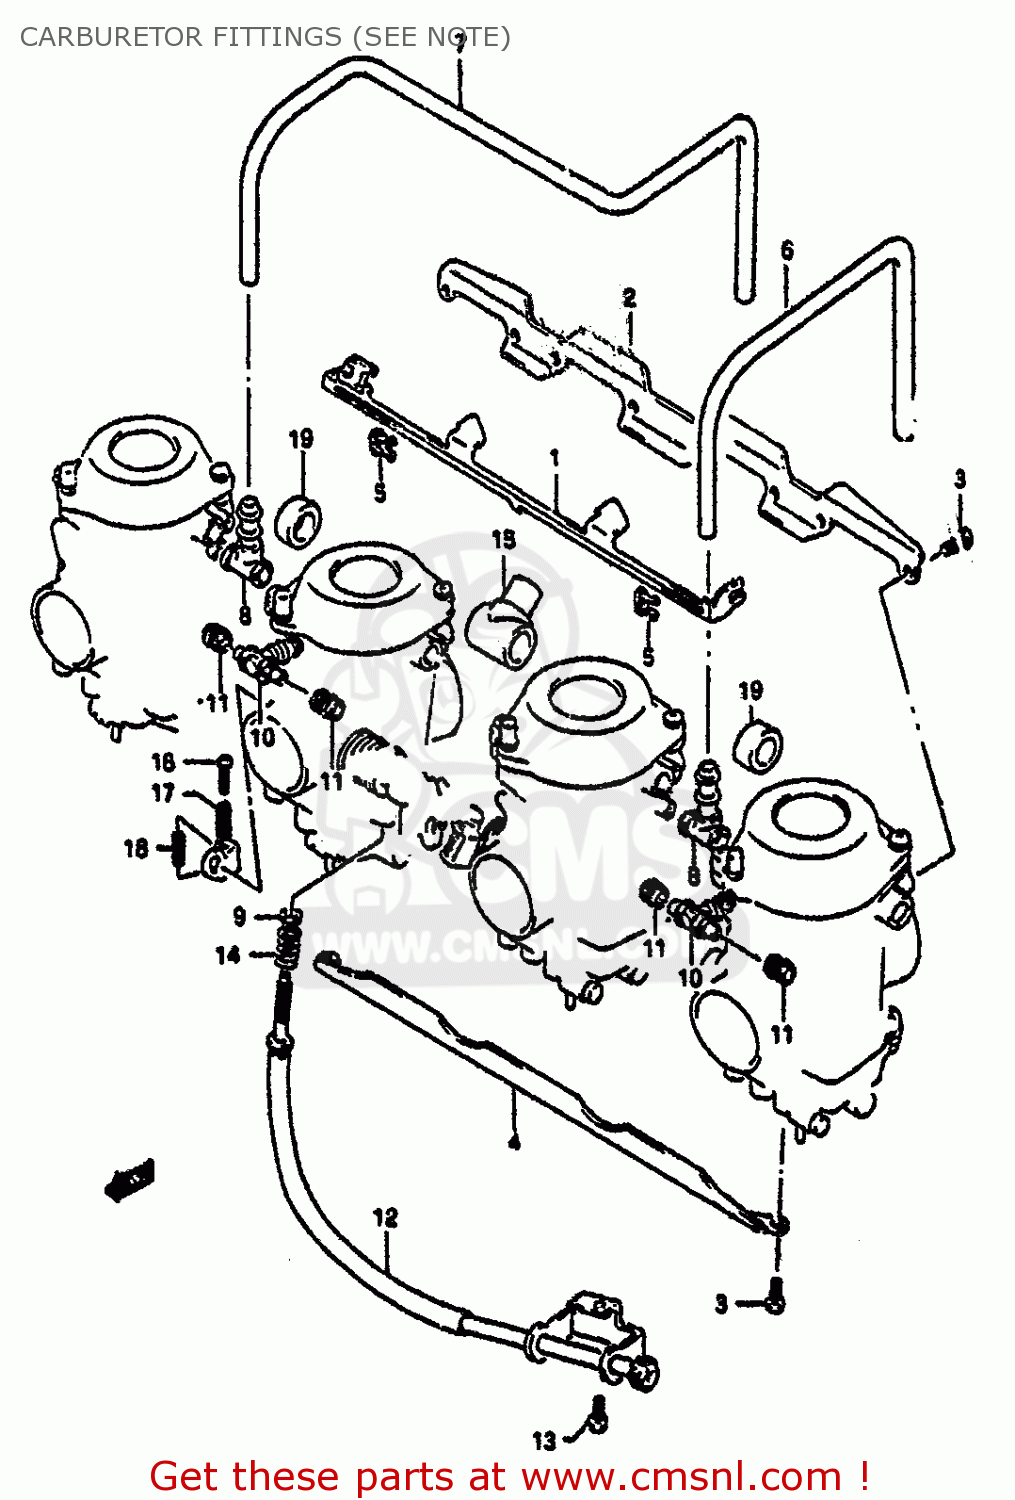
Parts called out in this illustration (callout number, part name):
1	LEVER
2	PLATE
3	CARBURETOR ASSY, MR
4	CARBURETOR ASSY, RH
5	HOLDER
6	HOSE
7	HOSE
8	HOSE
9	RING
10	NIPPLE
11	SEAL
12	NUT
13	SCREW 5X10
14	SPRING
15	SHAFT ASSY
16	SCREW
17	LEVER
18	SPRING
19	HOSE
20	SHAFT ASSY
21	SEAL
22	GASKET,THROTTLE SHAFT (NAS)
23	SCREW
24	VALVE, THROTTLE (120)
25	GASKET,FLOAT CHAMBER (NAS)
26	JET(40)
27	JET,NEEDLE,P-2
28	O RING
29	JET,MAIN(125)
30	RING
31	VALVE ASSEMBLY,NEEDLE
32	FLOAT ASSY
33	O RING
34	O RING
35	SCREW
36	SCREW
37	CAP
38	CLIP
39	PLUG,DRAIN
40	SHAFT ASSY
41	RING
42	COVER,DIAPHRAGM
43	CAP,STARTER
44	HOLDER,GUIDE
45	SPRING
46	PLUNGER ASSY
47	SCREW,PILOT
48	SPRING
49	WASHER
50	O RING,PILOT AIR SCREW
51	JET,AIR(1.2)
52	RING
